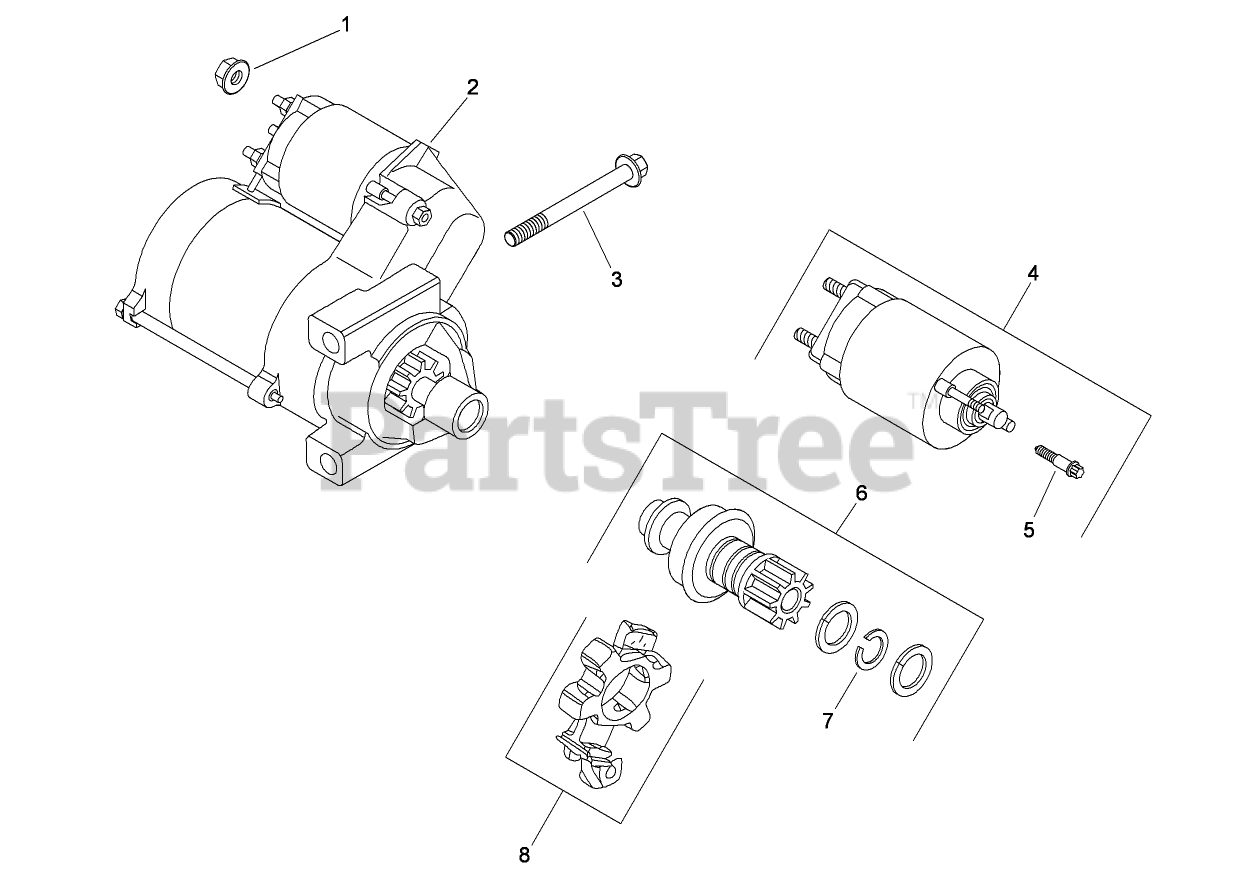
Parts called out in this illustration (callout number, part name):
1	NUT-FLANGE (M8X1.25)
2	STARTER ASM (SOLENOID SHIFT)
3	SCREW-FLG (M8X1.25X80)
4	Solenoid Kit (Includes 5)
5	SCREW-TORX HEAD, EXTERNAL
6	Pinion Drive Kit (Includes 7)
7	RING-RETAINING
8	BRUSH HOLDER KIT
